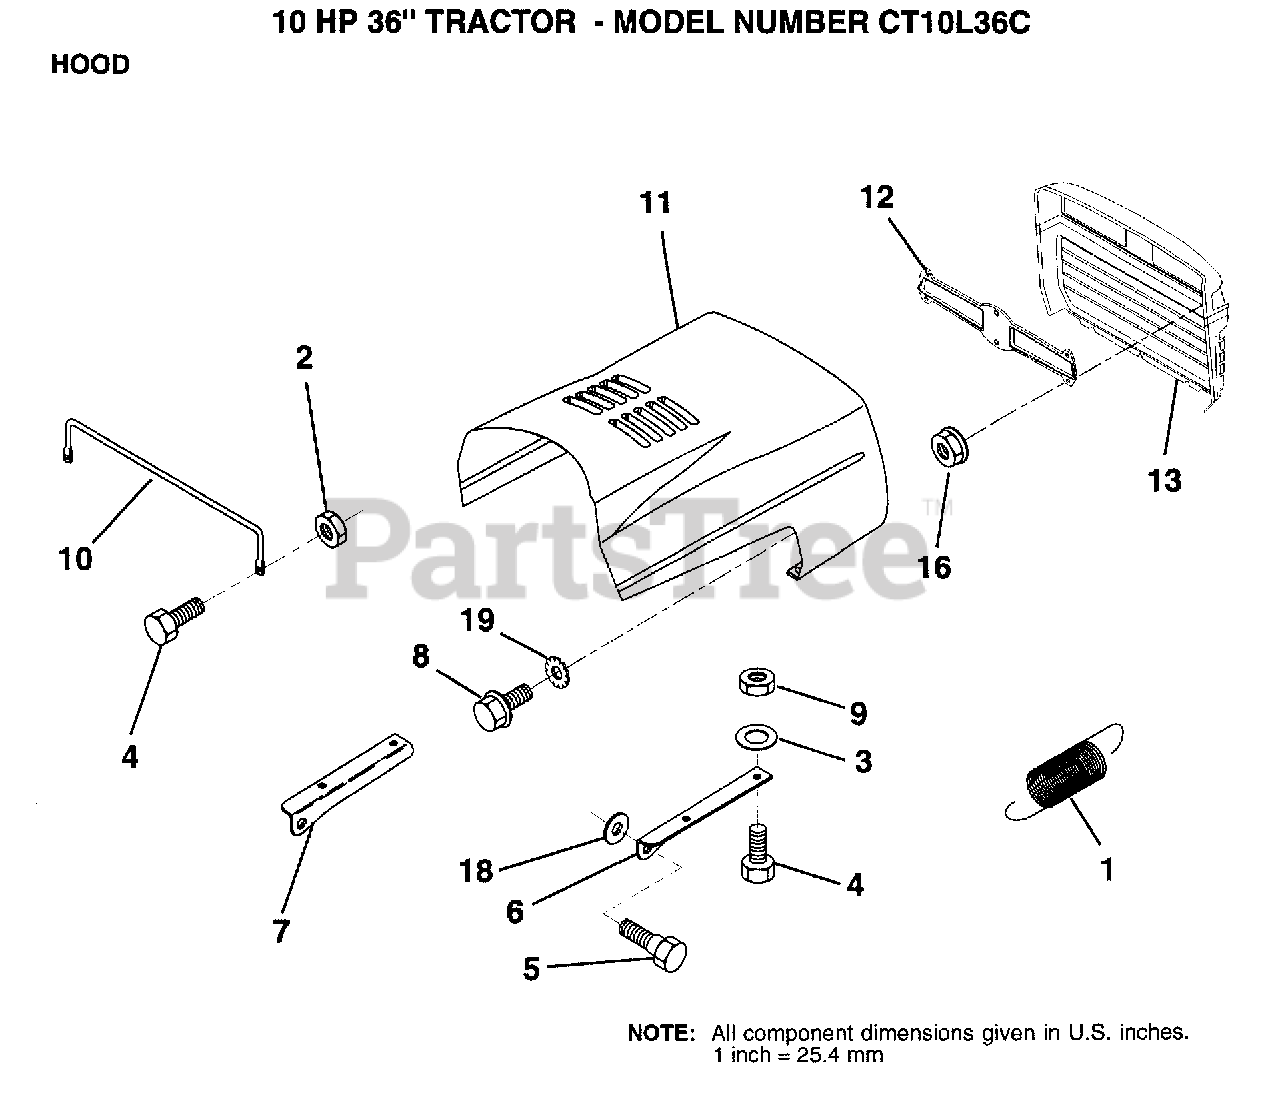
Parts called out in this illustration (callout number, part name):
1	EXT SPRING
2	NUT
3	WASHER
6	BRKT HOOD RH
7	BRKT HOOD LH
9	NUT
10	"BRACE,HOOD"
11	HOOD
13	GRILL (BLACK)
16	NUT
18	WASHER
19	LOCKWASHER GT
